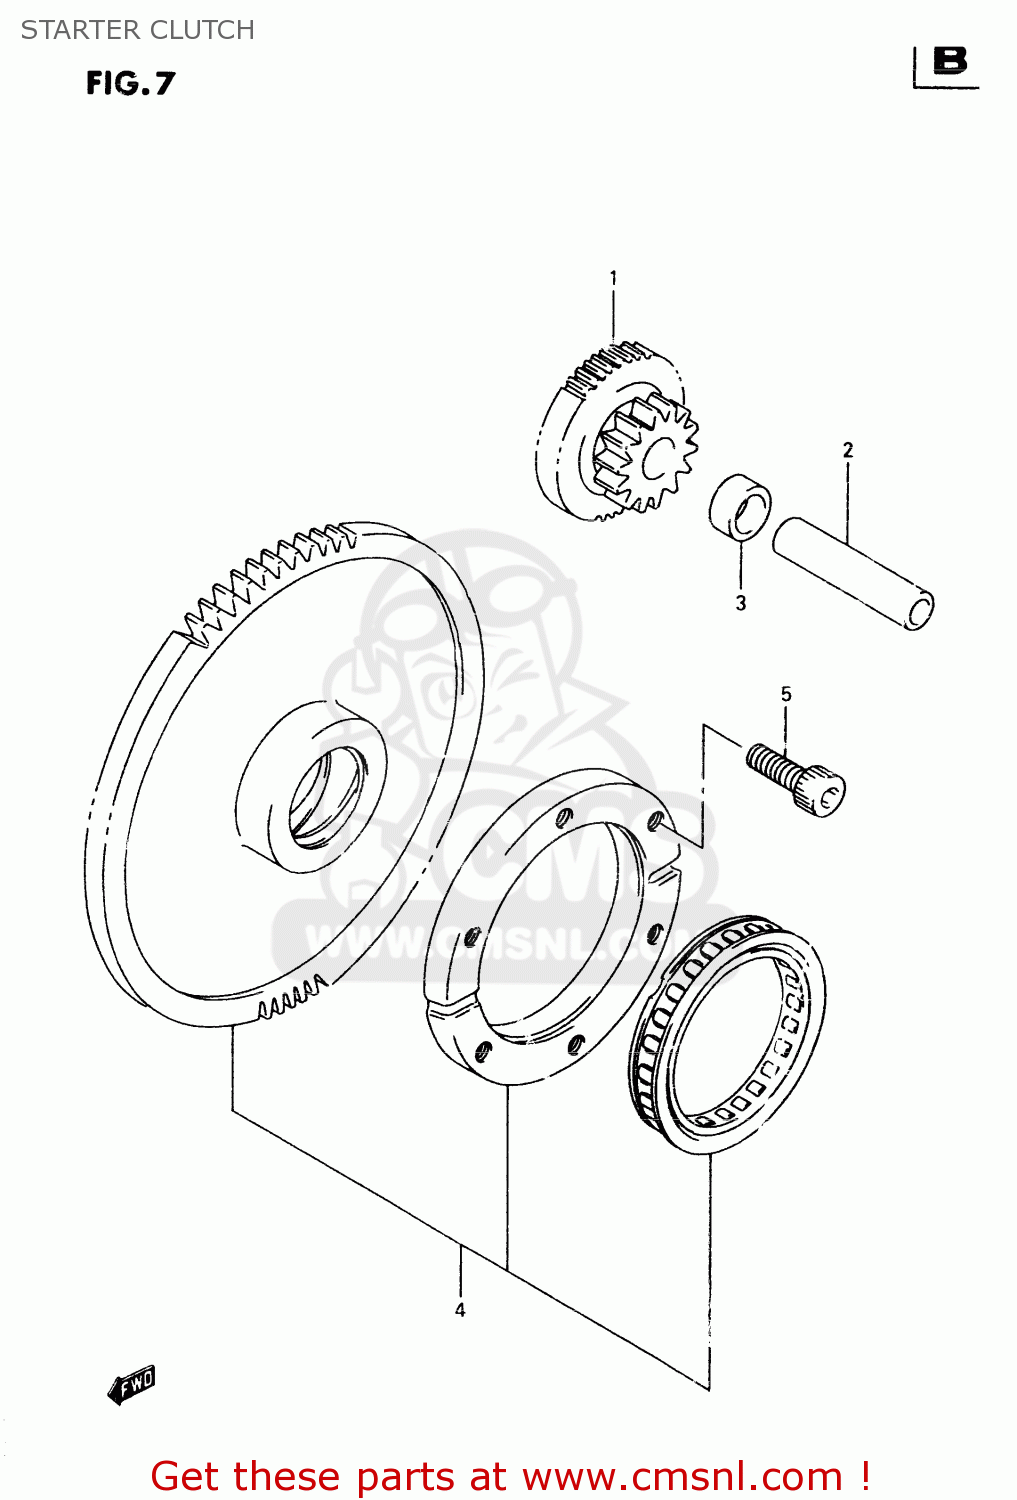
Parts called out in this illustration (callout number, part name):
1	GEAR,STARTER IDLE (NT
2	PIN(12X55.5)
3	SPACER(12.5X19X9.5)
4	CLUTCH SET,STARTER
5	BOLT
